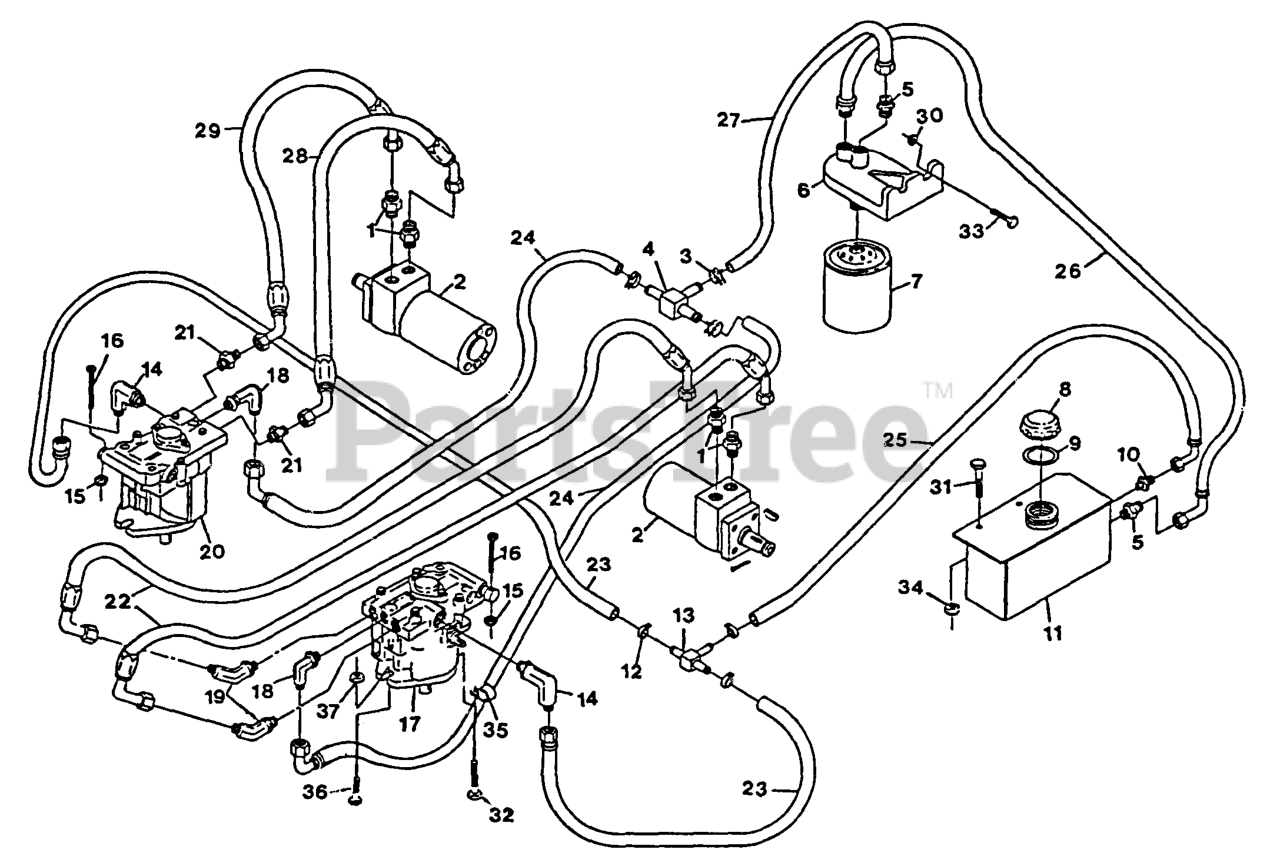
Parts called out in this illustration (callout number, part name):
2	HYD MOTOR ASM
3	CLAMP-HOSE
4	FITTING-TEE, HOSE
5	FITTING-STRAIGHT
9	GASKET-CAP, TANK
12	CLAMP-HOSE
13	FITTING-TEE, HOSE
14	FITTING-90 DEG
18	ELBOW,90 DEGREE
21	FITTING-STR
23	ASM,HOSE CASE DRAIN
25	HOSE ASSY TANK RETUR
27	ASM,HOSE CHARGE LINE
29	HOSE LH BPP/FMPW
35	CLIP-LOOM
